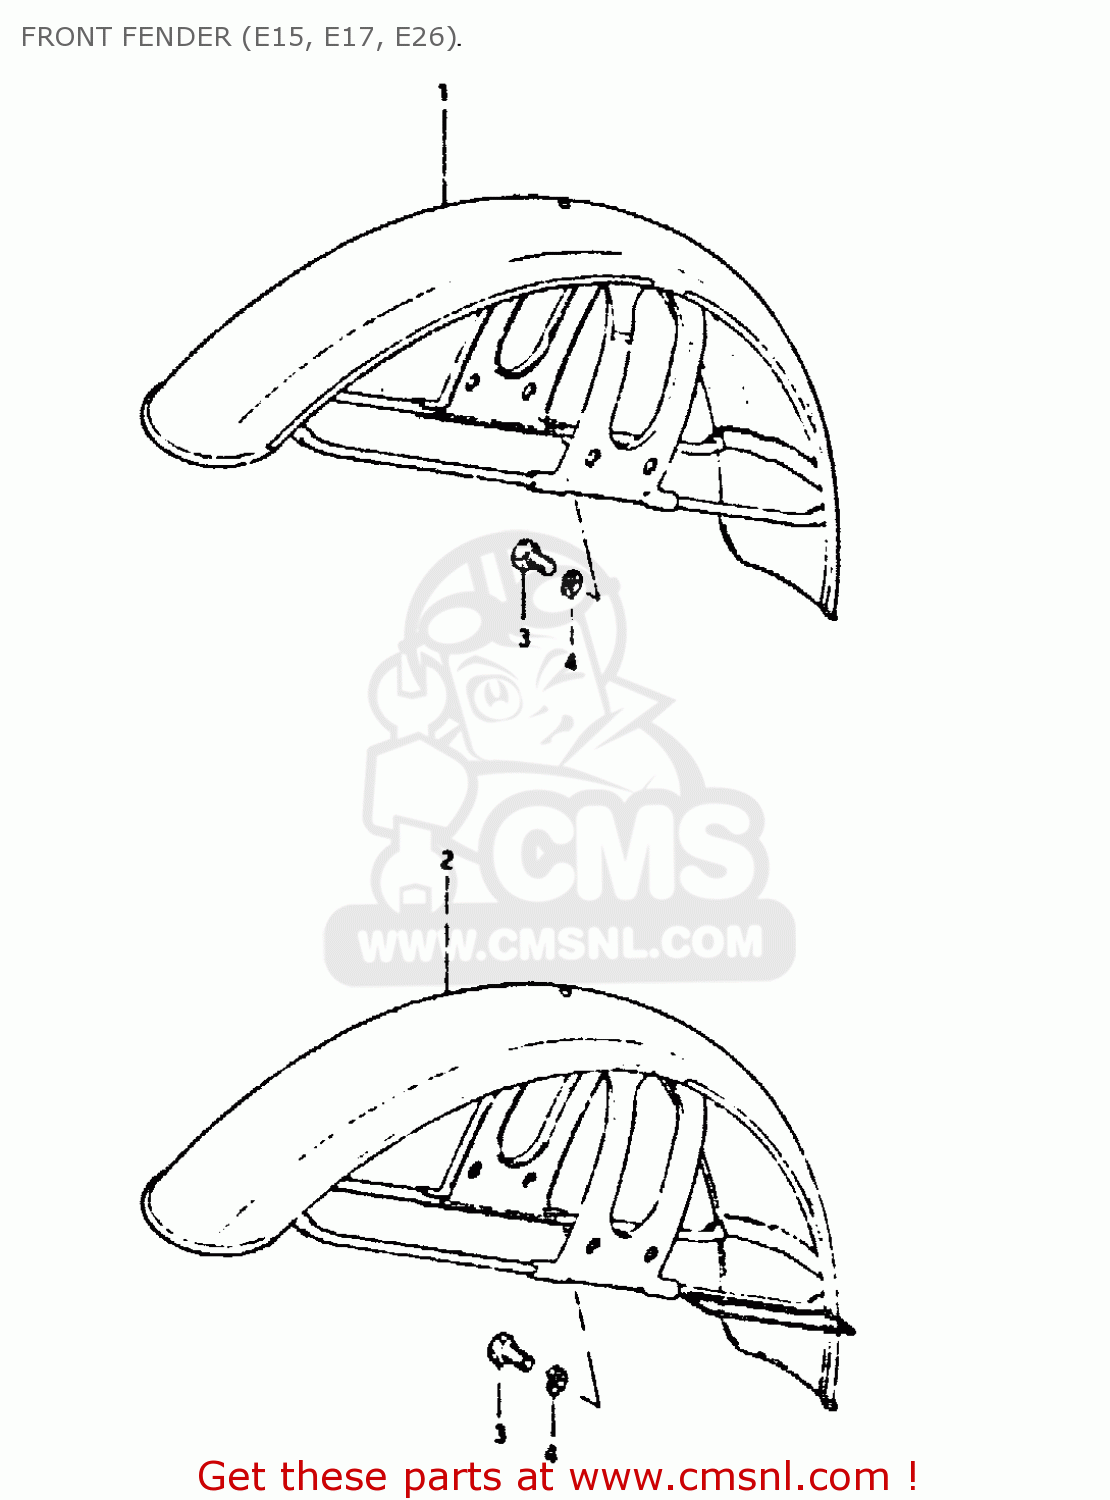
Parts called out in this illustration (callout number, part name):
1	FENDER, FRONT
2	FENDER,FR
3	BOLT
4	LOCK WASHER
